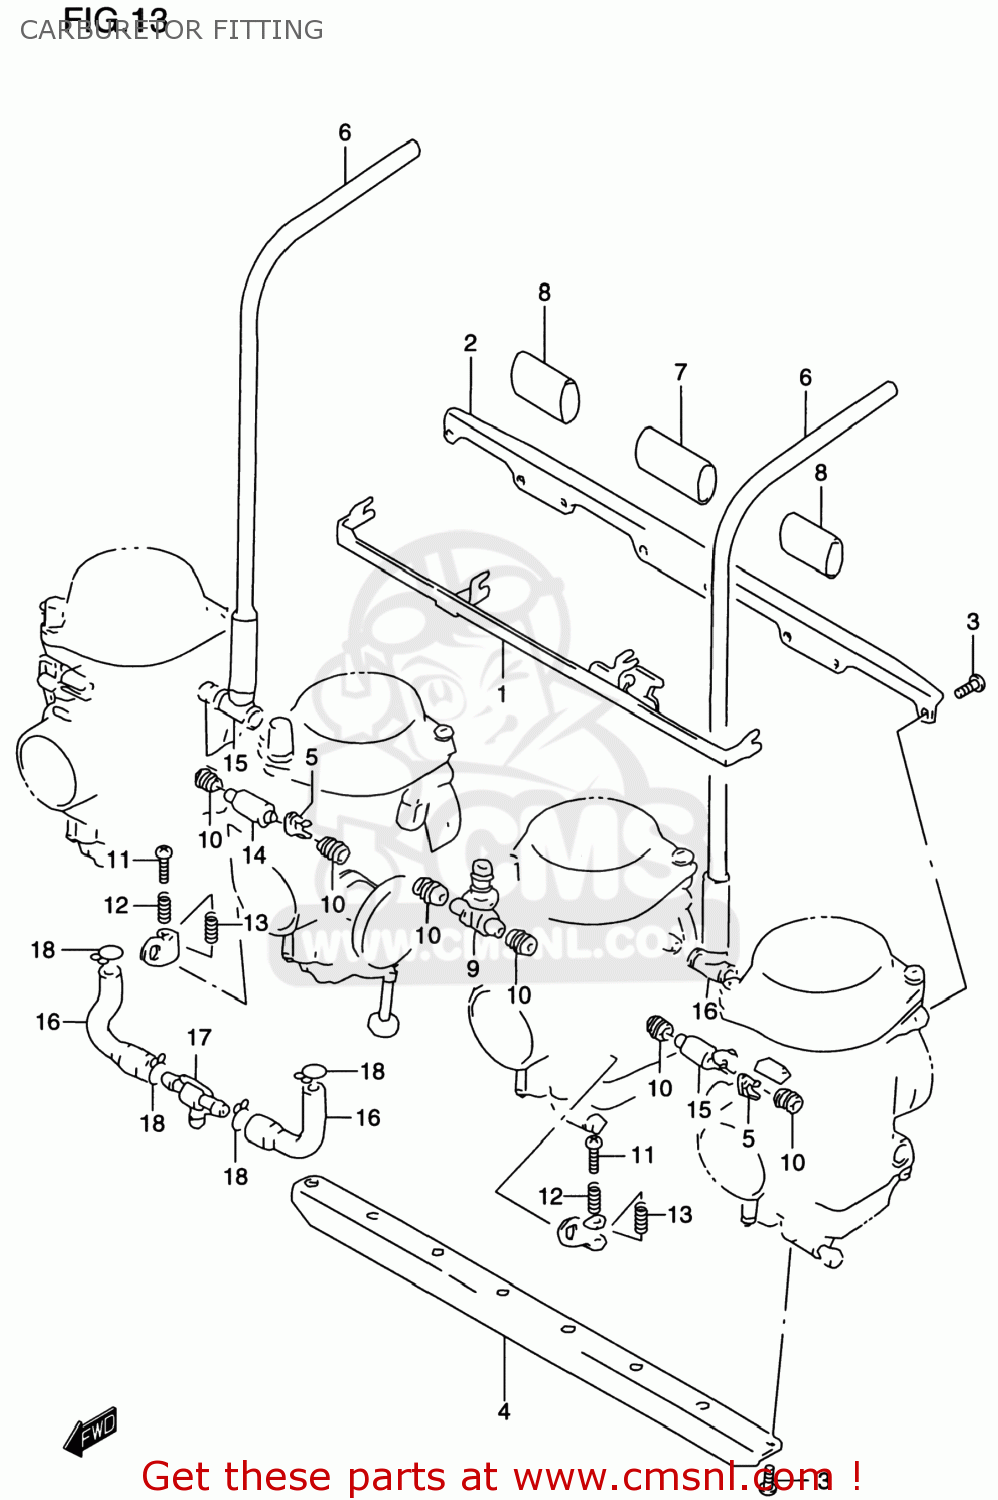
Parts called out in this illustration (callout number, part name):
1	LEVER
2	PLATE
3	SCREW
4	PLATE
5	HOLDER
6	HOSE(7X10.2X475)
7	HOSE(16X19X100)
8	HOSE(16X19X100)
9	NIPPLE
10	SEAL
11	SCREW
12	SPRING
13	SPRING
14	PIPE
15	HOSE
16	HOSE
17	NIPPLE
18	CLIP
